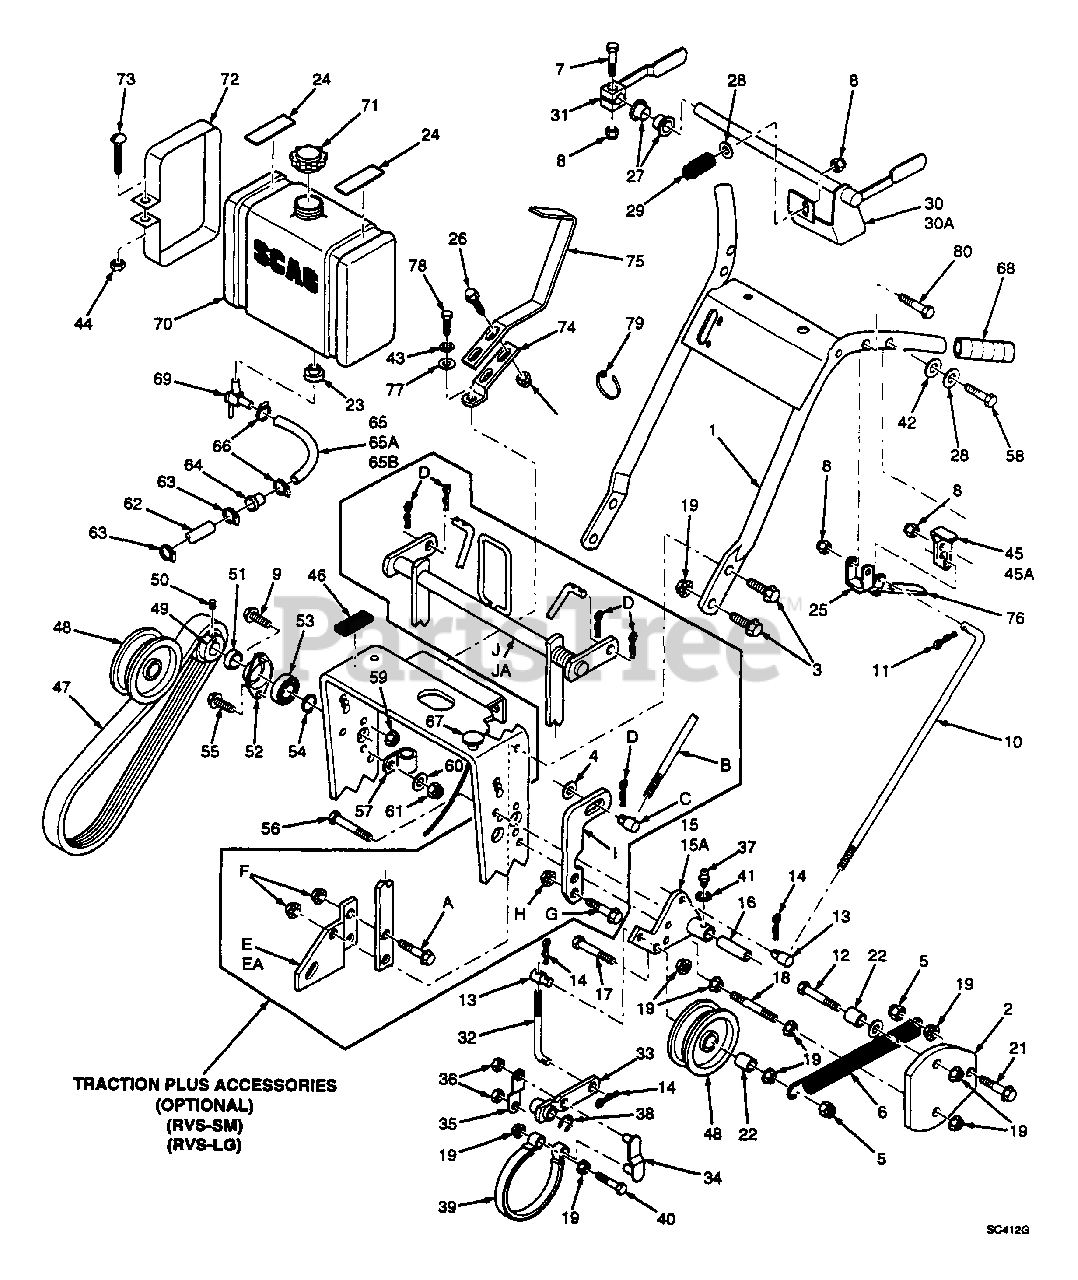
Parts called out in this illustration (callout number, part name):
1	Handle Assembly
2	Belt Guard
3	Capscrw, 3/8-16 x 1 Ser. Flange
4	Washer, 3/8" (.391 x .938 x .105)
5	Nut. 3/8-16 Elastic Stop
6	Spring, Idler
7	Bolt, 5/16-18 x 1-1/4 Hex Head
8	Nut, 5/16-18 Elastic Stop
9	Capscrew, 1/4-20 x 3/4" Hex Head
10	Control Rod, Steering
11	Hair Pin, Small
12	Bolt, 3/8-16 x 4-1/2 Hex Head
13	Swivel Joint
14	Hair Pin, Large .094 Diameter
15	Idler Bracket, RH
15A	Idler Bracket, LH
16	Idler Sleeve
17	Bolt, 3/8-16 x 3/4 Hex Head
18	Support Belt Guard
19	Nut, 5/16-18 Serrated Flange
21	Cpscrw, 3/16-18 x 1-1/4" Ser. Flng.
22	Spacer
23	Bushing
24	Rubber Pads, (Upper)
25	Steering Lever
26	Capscrew, 5/16-18 x 1" Ser. Flng.
27	Bushing
28	Washer, 5/16 (.375 x.875 x.083)
29	Spring, Operator Presence
30	Operator Presence Lever, LH (Small Frame)
30A	Operator Presence Lever, LH (Large Frame)
31	Operator Presence Lever, RH
32	Brake Rod
33	Brake Lever
34	Brake Link
35	Brake Link Plate
36	Nut, 3/8 Push-On
37	Grease Fitting, Straight 1/4-28
38	Retaining Ring, 5/6 Ext. "E"
39	Brake Band
40	Bolt, 3/8-16 x 2 Hex Head
41	1/4" Internal Tooth Lockwasher
42	Curved Spring Washer
43	Lockwasher, 1/4 Spring
44	Nut, 1/4-20 Hex
45	Neutral Latch, RH
45A	Neutral Latch, LH
46	Rubber Pad (Lower)
47	Belt, Wheel Drive
48	Idler Pulley, Wheel Drive
49	Pulley, Jackshaft
50	Setscrew, Hex Socket Knurl Cup Pt. 5/16-18
51	Spacer, Jackshaft Pulley
52	Range, Jackshaft Bearing
53	Bearing, Jackshaft
54	Retaining Ring, 5/8 Ext. Basic
55	Capscrew, 1/4-20 x 1" Ser. Flange
56	Bolt, 1/4-20 x 6" Carriage
58	Bolt, 5/16-18 x 2" Hex Head
59	Nut, 1/4-20 Serrated Flange
60	Flatwasher, 5/16 (.375 x .875 x .083)
61	Nut, 1/4-20 Elastic Stop
62	Fuel Hose
63	Fuel Hose Clamp
64	Fuel Filter
65	Fuel Hose, 1/4" ID, 10"
65A	Fuel Hose, 1/4" ID, 20"
65B	Fuel Hose, 1/4" ID, 23"
66	Clamp, Fuel Hose
67	Choke Control
68	Grip, Handle
69	Valve, Fuel Shut Off
70	Fuel Tank Assy.
71	Fuel Tank Cap
72	Strap, Fuel Tank
73	Screw, 1/4-20 x 2" Round Hd Slotted
74	Shift Lever
75	Shift Lever Extension
76	Grip, Steering Lever
77	Washer, 1/4 (.265 x .875 x .125)
78	Bolt, 1/4-28 x 3/4" Hex Head Grd 8
79	Cable Tie
80	Bolt, 5/16-18 x 2-1/2"
A	Capscrew, 3/8-16 x 1" Ser. Flng
B	Rod, Traction Control
C	Swivel Joint
D	Hair Pin, Large .094 Dia.
E	Mounting Brkt. LH Traction Cont.
EA	Mounting Brkt. RH Traction Cont.
F	Nut, 30-16 Serrated Flange
G	Capscrew, 5/16-18 x 3/4" Ser. Flng.
H	Nut, 5/16-18 Serrated Flange
I	Traction Lever, LH
IA	Traction Lever, RH
J	Traction Lever Wldmnt. (Small Fm.)
JA	Traction Lever Wldmnt. (Large Fm.)
